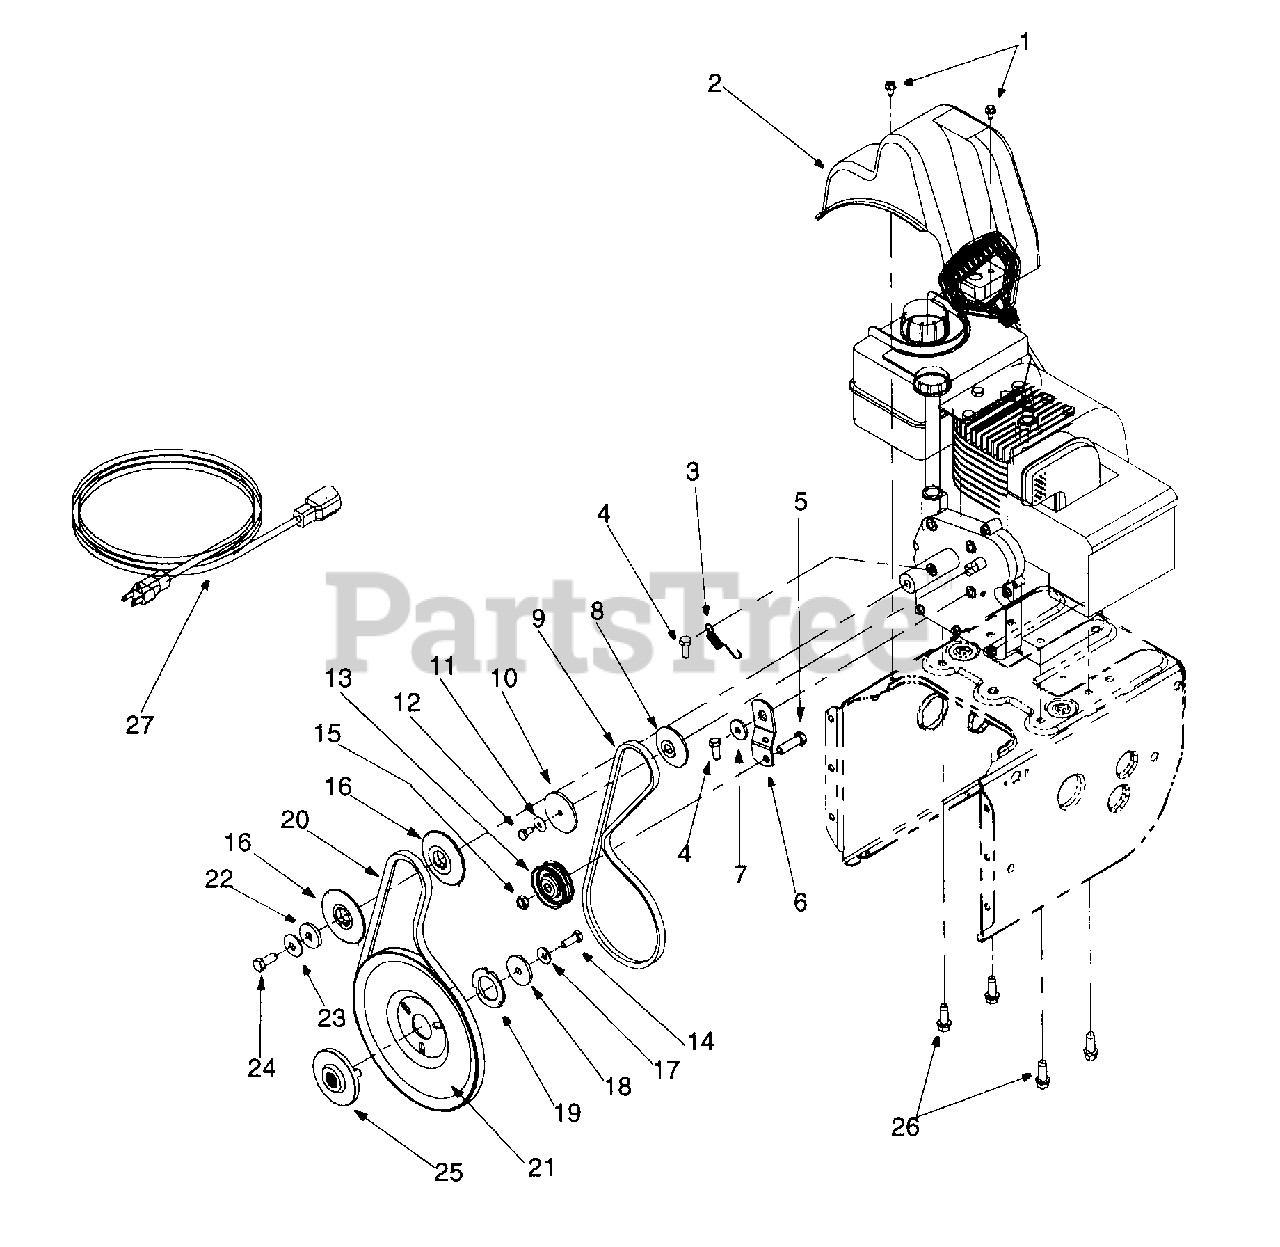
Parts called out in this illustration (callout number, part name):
1	Hex Washer Screw 1/4-20 x.5
2	Belt Cover
3	Extension Spring
4	Hex Screw 5/16-24 x .75
5	Hex Cap Screw 3/8-16 x 1.25
8	Pulley Half
9	V-Belt
10	Pulley Half
11	Bell Washer
12	Hex Cap Screw 1/4-28 x .50
13	Flat Idler
14	Lock Cap Screw 5/16-24
15	Lock Jam Nut 3/8-16
16	Pulley Half
17	Bell Washer
18	Flat Washer
19	Washer
20	Belt
21	Auger Pulley
22	Flat Washer
23	Bell Washer
24	Hex Cap Screw 3/8-24
25	Pulley
26	Hex Washer Screw 3/8-16 x 1.0
27	Extension Cord
